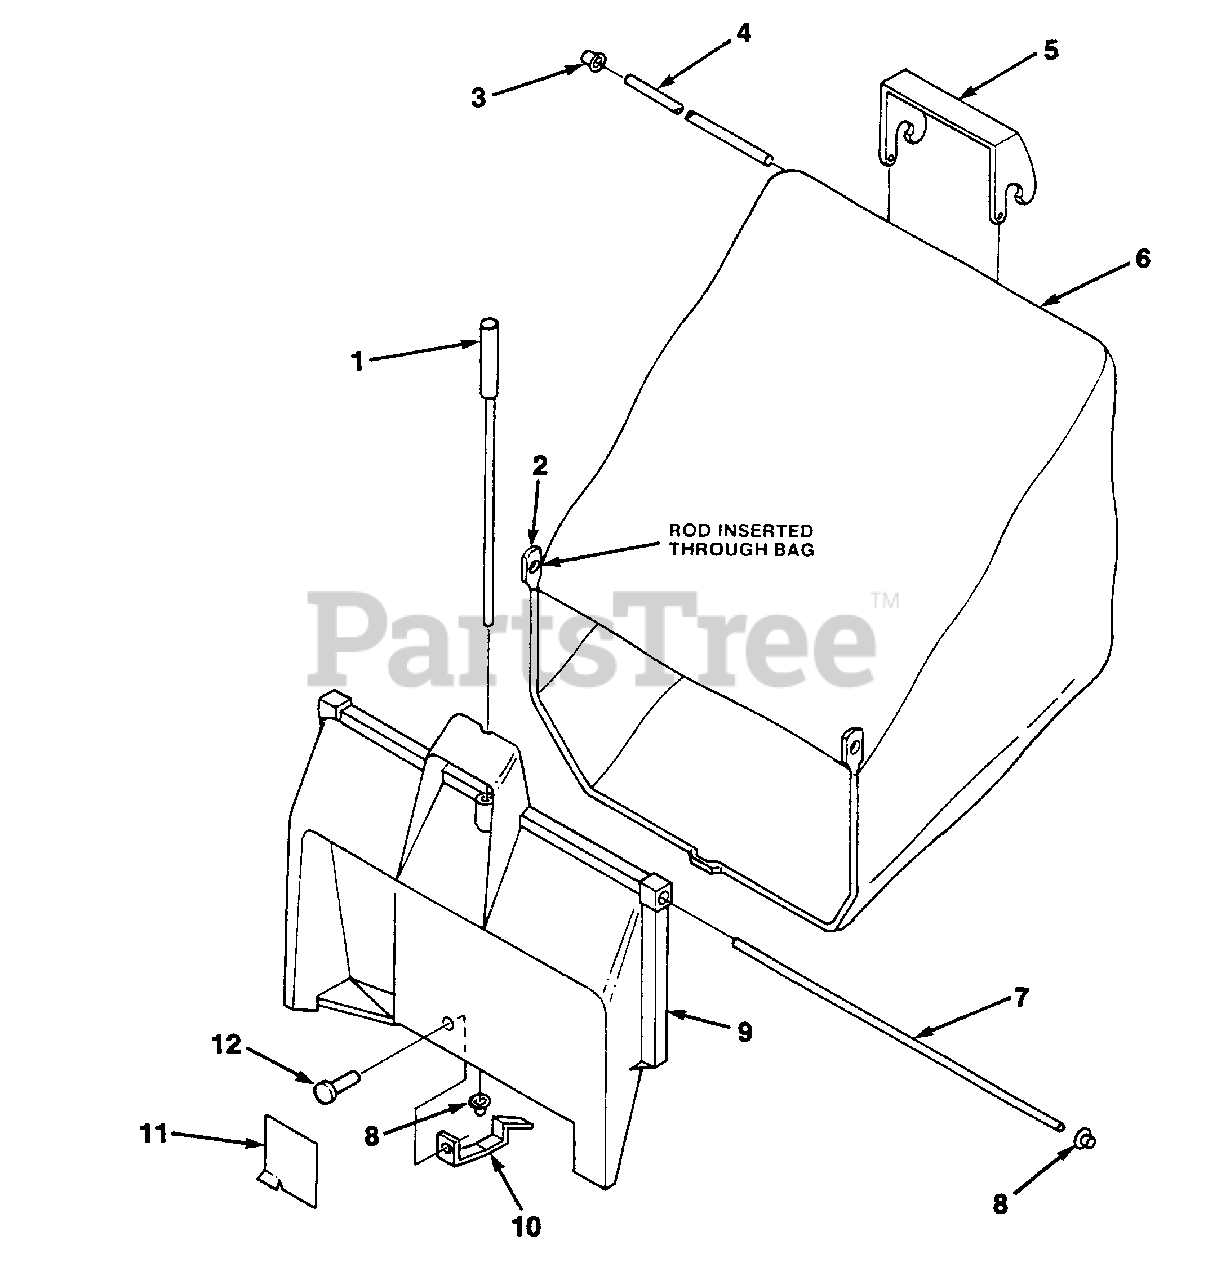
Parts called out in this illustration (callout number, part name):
1	LATCH- Rod
2	ROD- Bag support
4	ROD- Upper bag
6	CATCHER- Grass
7	ROD- Bag hinge
9	ADAPTOR- Bag
11	DEFLECTOR
